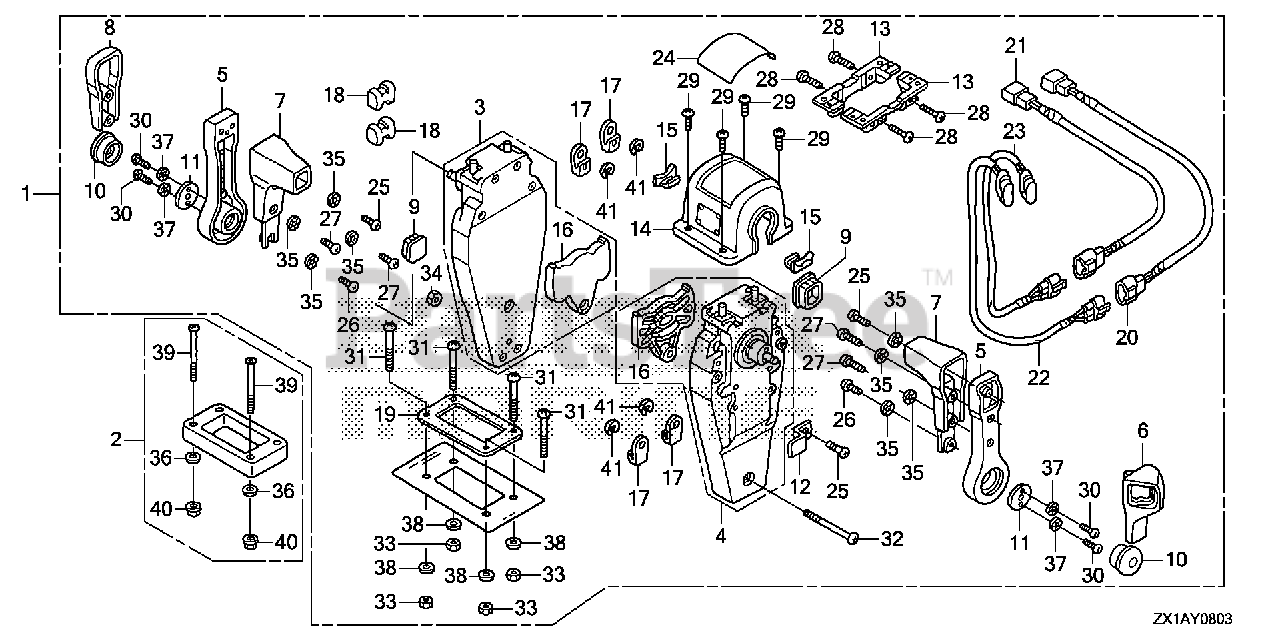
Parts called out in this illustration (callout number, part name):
1	BOX KIT, REMOTE CONTROL (TOP MOUNT DUAL)(L)
2	SPACER KIT, REMOTE CONTROL BOX (TOP MOUNT DUAL)
3	HOUSING ASSY., L. (INNER) (TOP MOUNT)
4	HOUSING ASSY., R. (INNER) (TOP MOUNT)
5	HANDLE, REMOTE CONTROL
6	COVER, R. GRIP
7	GRIP, REMOTE CONTROL HANDLE
8	COVER, DUAL GRIP
9	CAP, GRIP
10	BUTTON, THROTTLE
11	PLATE, HANDLE
12	PLATE, CABLE CLAMP
13	BRACKET, REMOTE CONTROL HOUSING
14	HOUSING, DUAL REMOTE CONTROL BOX
15	HOUSING, LEAD
16	PLATE, DWELL
17	TERMINAL, CABLE
18	SPACER, CABLE CLAMP
19	GASKET, DUAL
20	SUB-HARNESS ASSY., POWER TRIM-TILT (A)
21	SUB-HARNESS ASSY., POWER TRIM-TILT (B)
22	SWITCH ASSY., POWER TRIM-TILT (A)
23	SWITCH ASSY., POWER TRIM-TILT
24	MARK, REMOTE CONTROL (DUAL)
25	SCREW, PAN (5X16)
26	SCREW, PAN (5X10)
27	SCREW, PAN (5X20)
28	SCREW, PAN (5X18)
29	SCREW, PAN (4X10)
30	SCREW, PAN (6X18)
31	SCREW, PAN (5X40)
32	SCREW, PAN (5X55)
33	NUT, HEX. (5MM)
34	NUT, HEX. (5MM)
35	WASHER, LOCK (5MM)
36	WASHER, PLAIN (5MM)
37	WASHER, LOCK (6MM)
38	WASHER, PLAIN (5MM)
39	SCREW, PAN (5X65)
40	NUT, HEX. (5MM)
41	E-RING (6MM)
